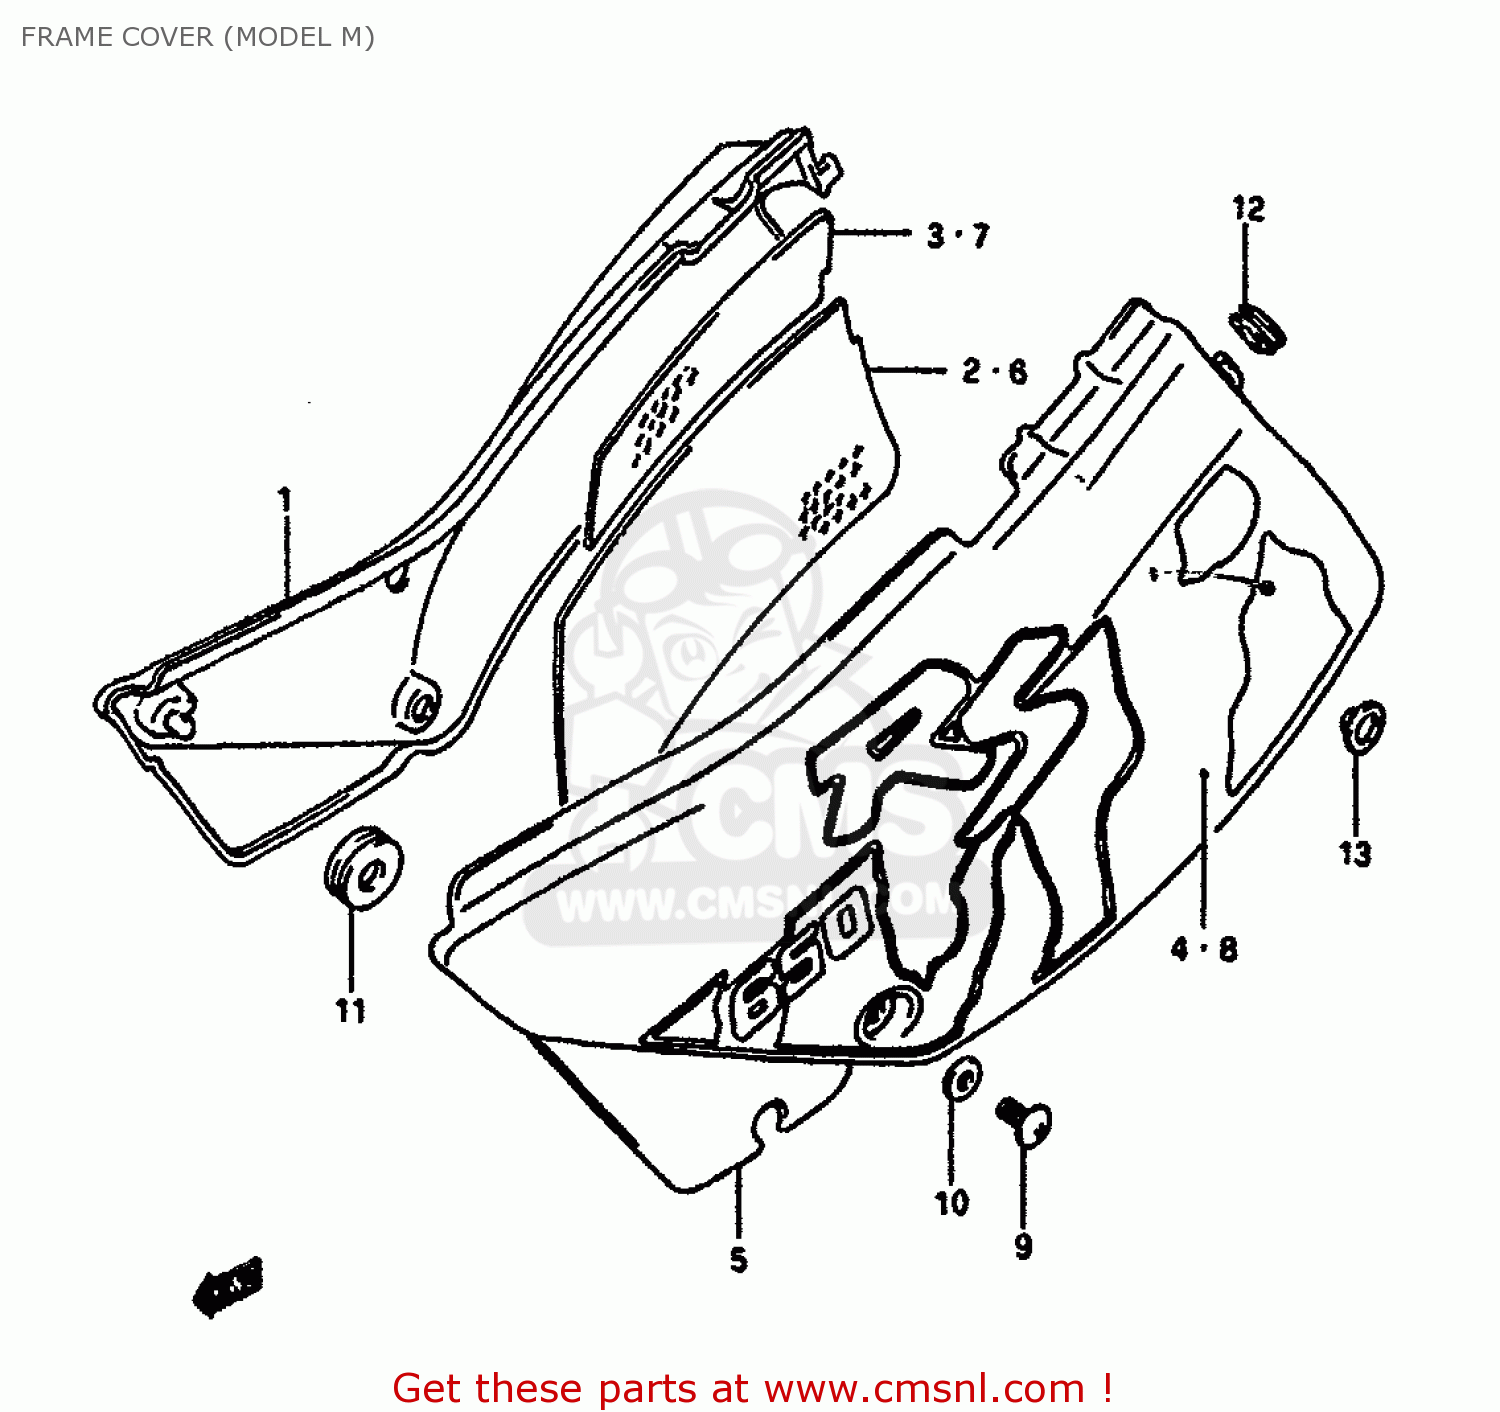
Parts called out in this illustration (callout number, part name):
1	COVER,FRAME RH (RED)
2	HEATSHIELD,LWR,R
3	SHIELD,FRAME C
4	TAPE,RH
5	COVER,FRAME LH (RED)
6	HEATSHIELD,LWR,L
7	SHIELD,FRAME COVER NO.2,L
8	TAPE,LH
9	SCREW 6X12
10	WASHER
11	CUSHION
12	CUSHION
13	CUSHION
